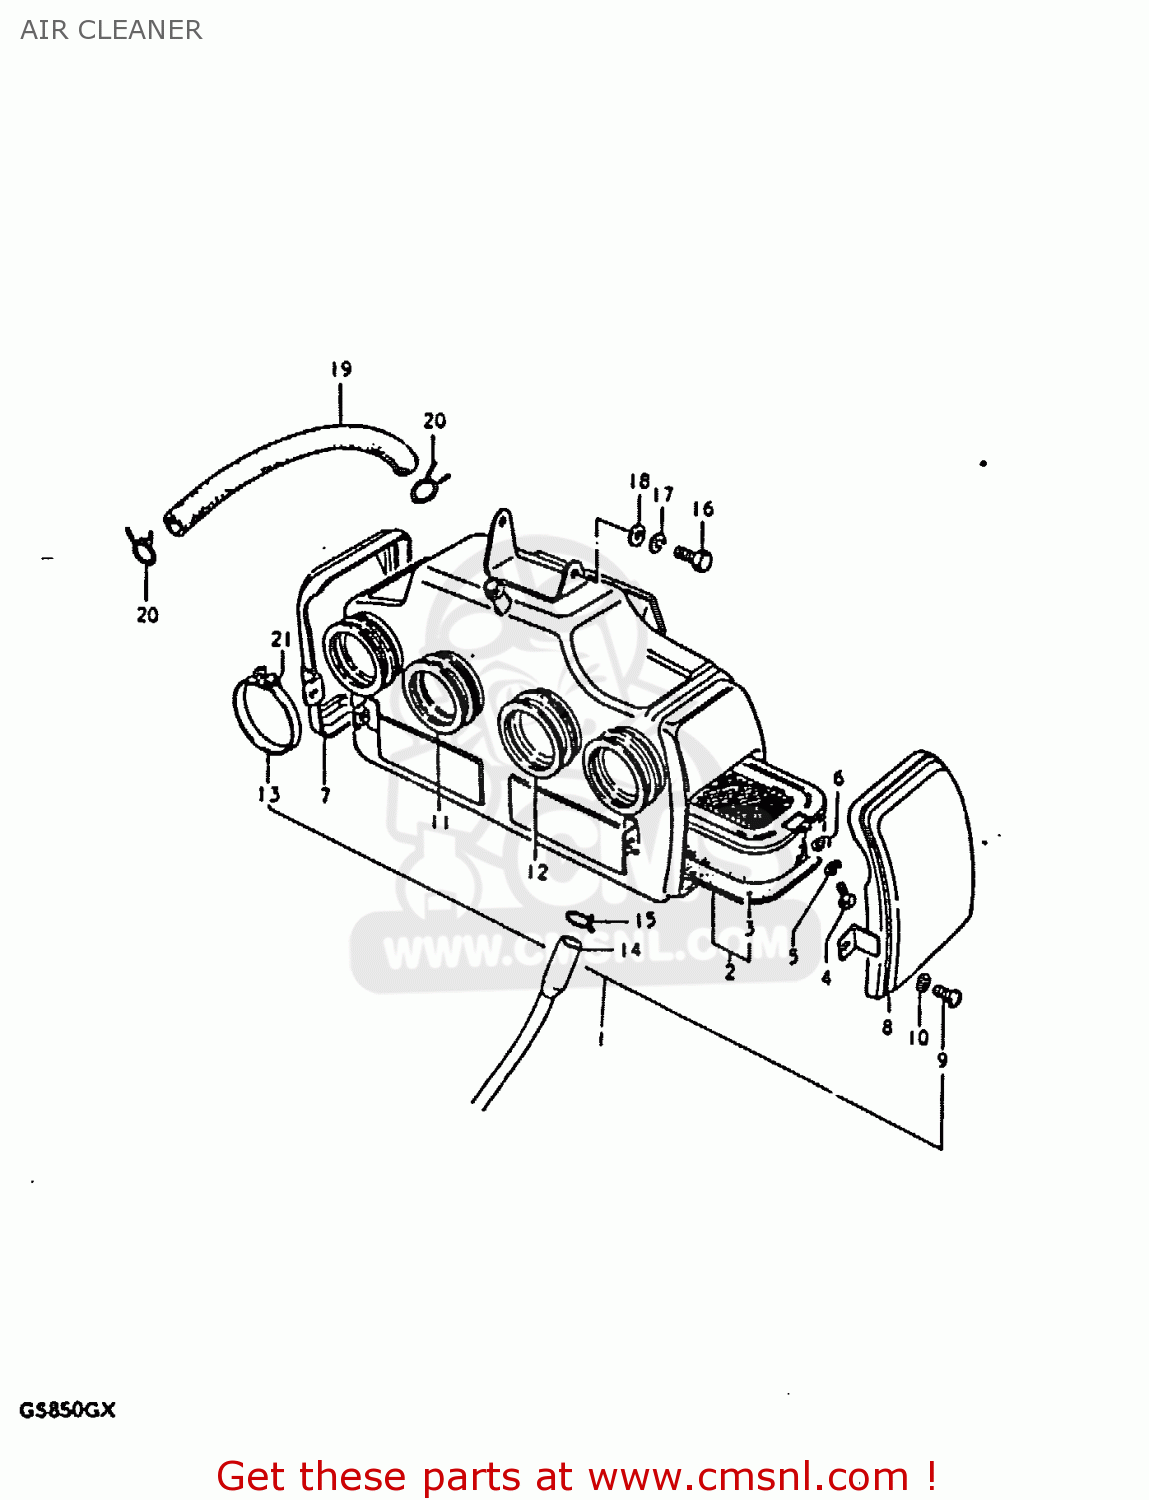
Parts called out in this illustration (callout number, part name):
1	CLEANER ASSEMBLY,AIR
2	FILTER ASSY,AIR CLEANER
3	FILTER
4	SCREW
5	LOCK WASHER
6	WASHER
7	CAP,AIR CLEANER
8	COVER, LH
9	SCREW
10	WASHER
11	HOSE,R
12	HOSE,L
13	CLAMP
14	14-2
15	16
16	BOLT
17	LOCK WASHER
18	WASHER 6MM
19	HOSE
20	CLIP
